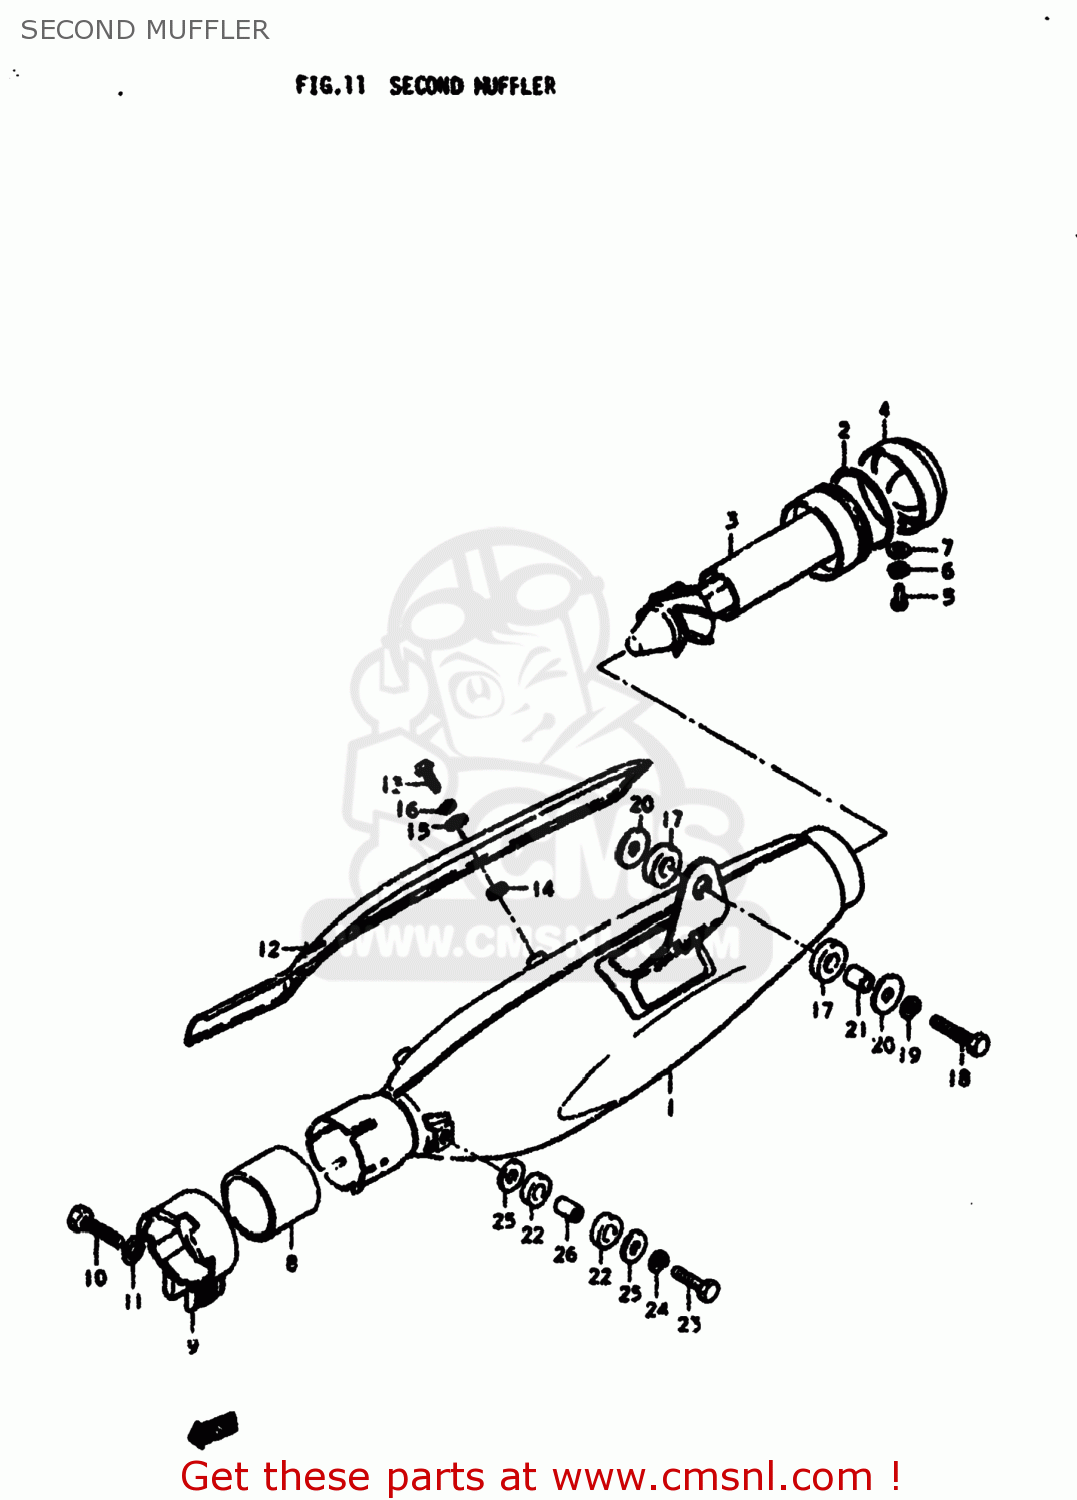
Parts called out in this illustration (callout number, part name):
1	MUFFLER ASSEMBLY
2	O-RING (D:3.5 ID:54.4)
3	TUBE,MUFFLER CLEAN OUT
4	COVER,SECOND MUFFLER TAIL
5	SCREW(6X8)
6	LOCK WASHER
7	WASHER
8	CONNECTOR,MUFFLER
9	CLAMP
10	BOLT 8X35
11	WASHER
12	COVER,SECOND MUFFLER
13	SCREW 6X12
14	GASKET 6.2X12X1.5 (MCA)
15	WASHER
16	LOCK WASHER
17	CUSHION
18	BOLT (8X30)
19	LOCK WASHER
20	WASHER (8.5X29X1.6)
21	SPACER (8.6X13.8X13)
22	CUSHION
23	BOLT
24	LOCK WASHER
25	WASHER
26	SPACER (8.6X13.8X8)
